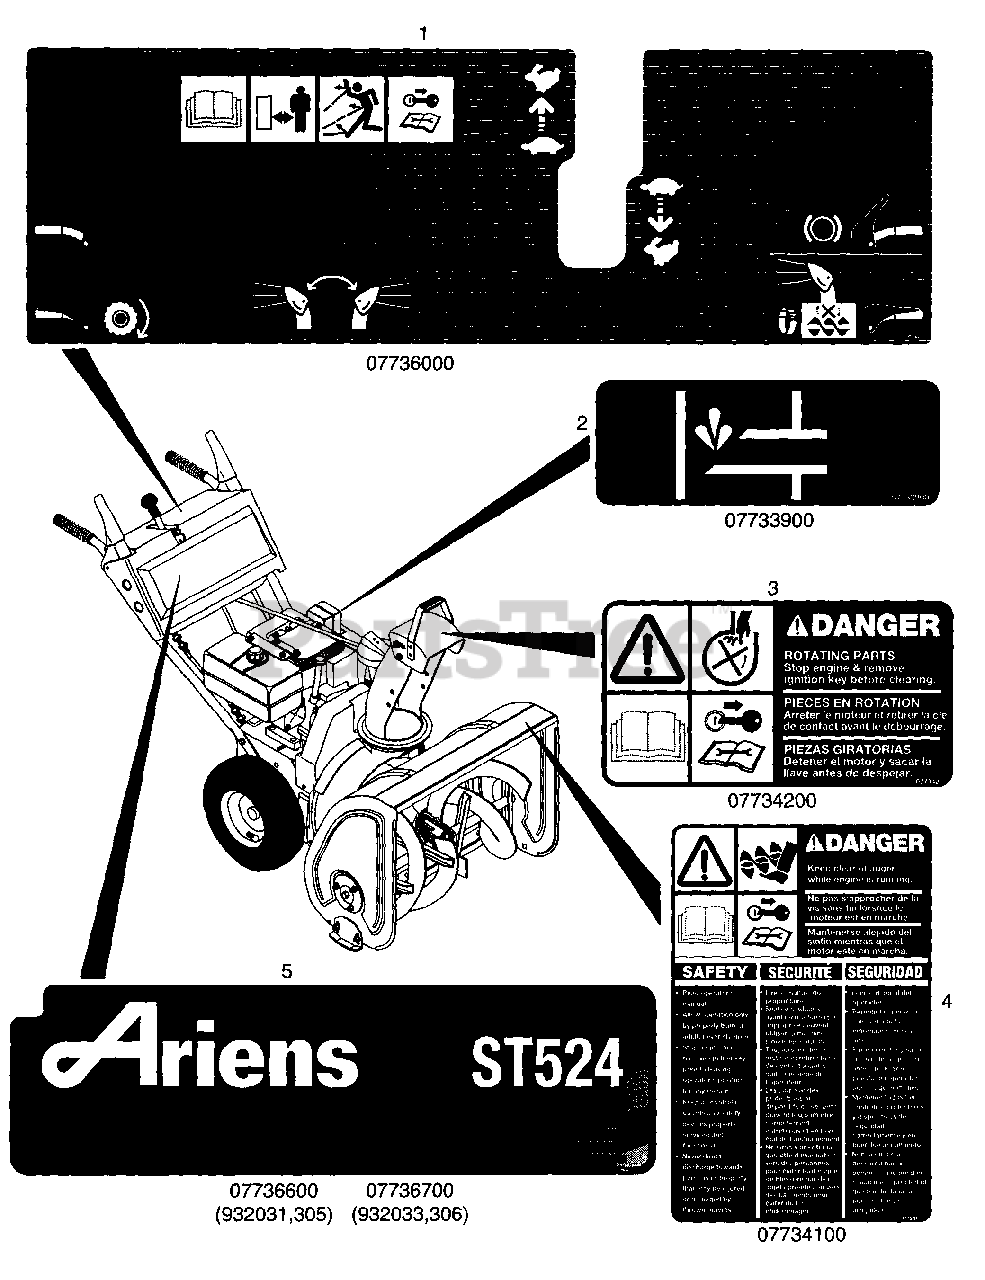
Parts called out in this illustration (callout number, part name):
1	DECAL, DASH
2	DECAL, PRIMER "TECUMSEH'S"
3	DECAL, DANGER - ROT. PARTS
4	DECAL, DANGER
5	DECAL - ST524
5	DECAL - ST724
